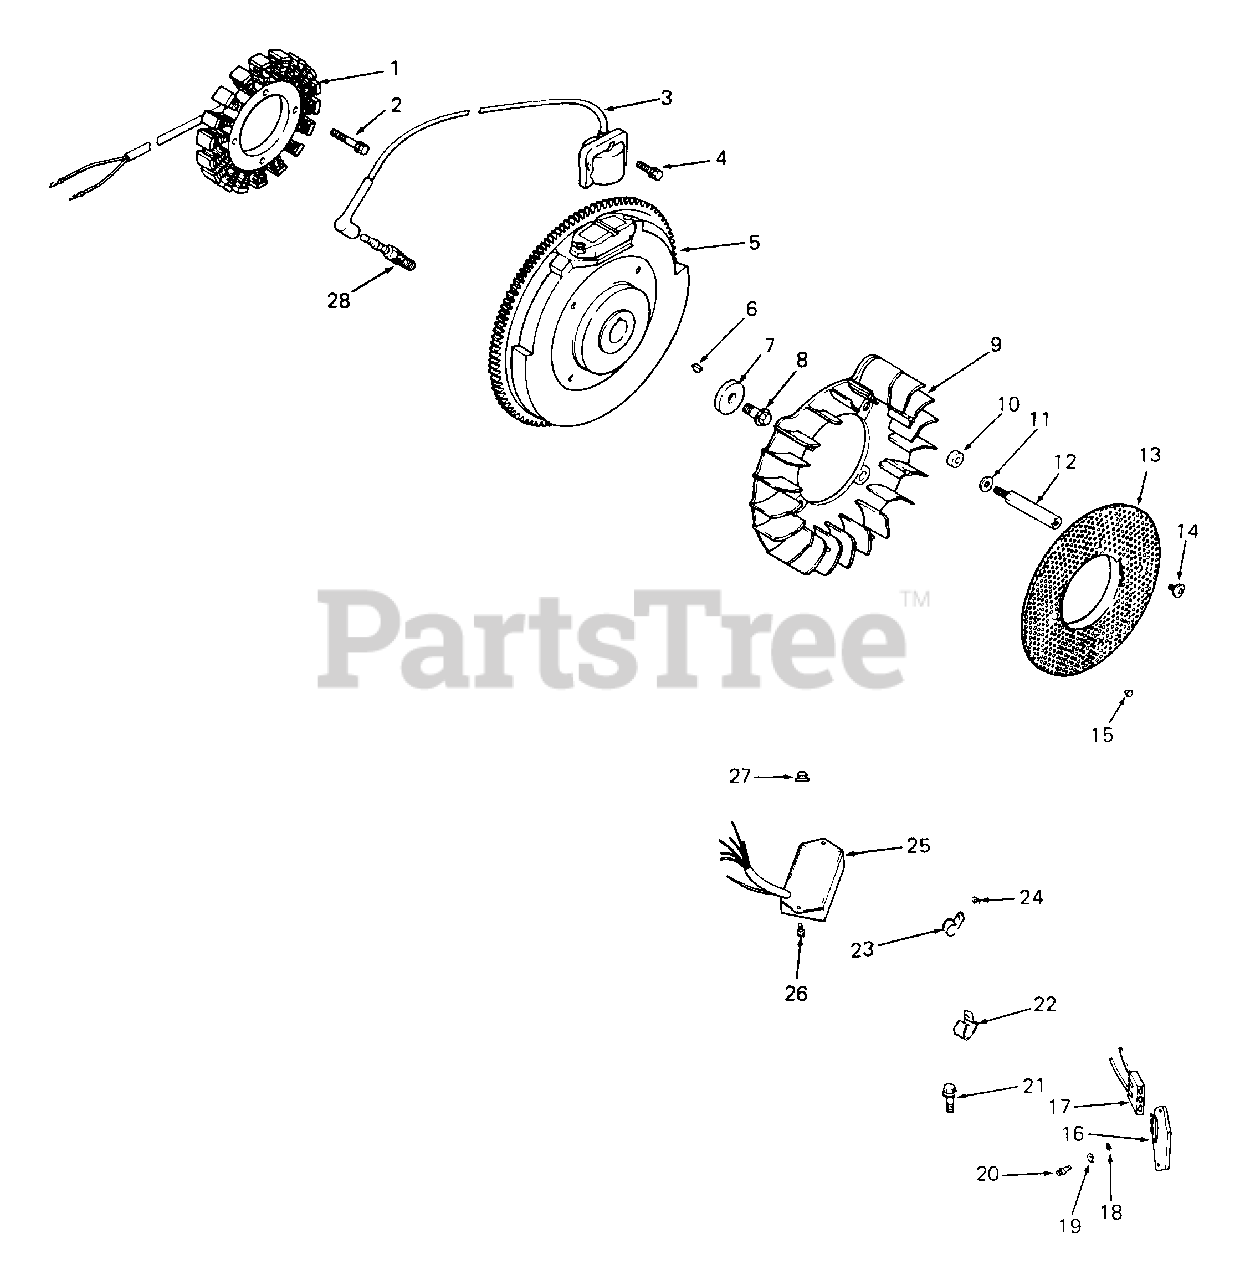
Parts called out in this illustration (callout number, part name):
1	Stator, 15 Amp
2	Screw, Stator Mtg, M5 x 0.8 x 25
3	Module, Ignition
4	Screw, Ignition Module, M5 x 0.8 x 20
5	Flywheel Assembly
7	Washer, Flywheel Mtg
8	Screw, Flywheel Mtg, M10 x 1.5 x 45.8
10	Spacer, Fan
11	Washer, Plain, 1/4
12	Stud, Grass Screen
13	Screen, Grass
14	Screw, M6 x 1.0 x 10
16	Regulator-Rectifier, 15 Amp
17	Connector, 3 contact
18	Washer, Plain, 1/4
19	Washer, Plain, 1/2
20	Screw, Phillips
21	Screw, Drive Shaft Adapter, M8 x 1.25 x 25
22	Clip, Cable
24	Washer, Plain, 1/4
25	Module, Speed Advance
26	Screw, Phillips
27	Nut, Plastic
28	Spark Plug
